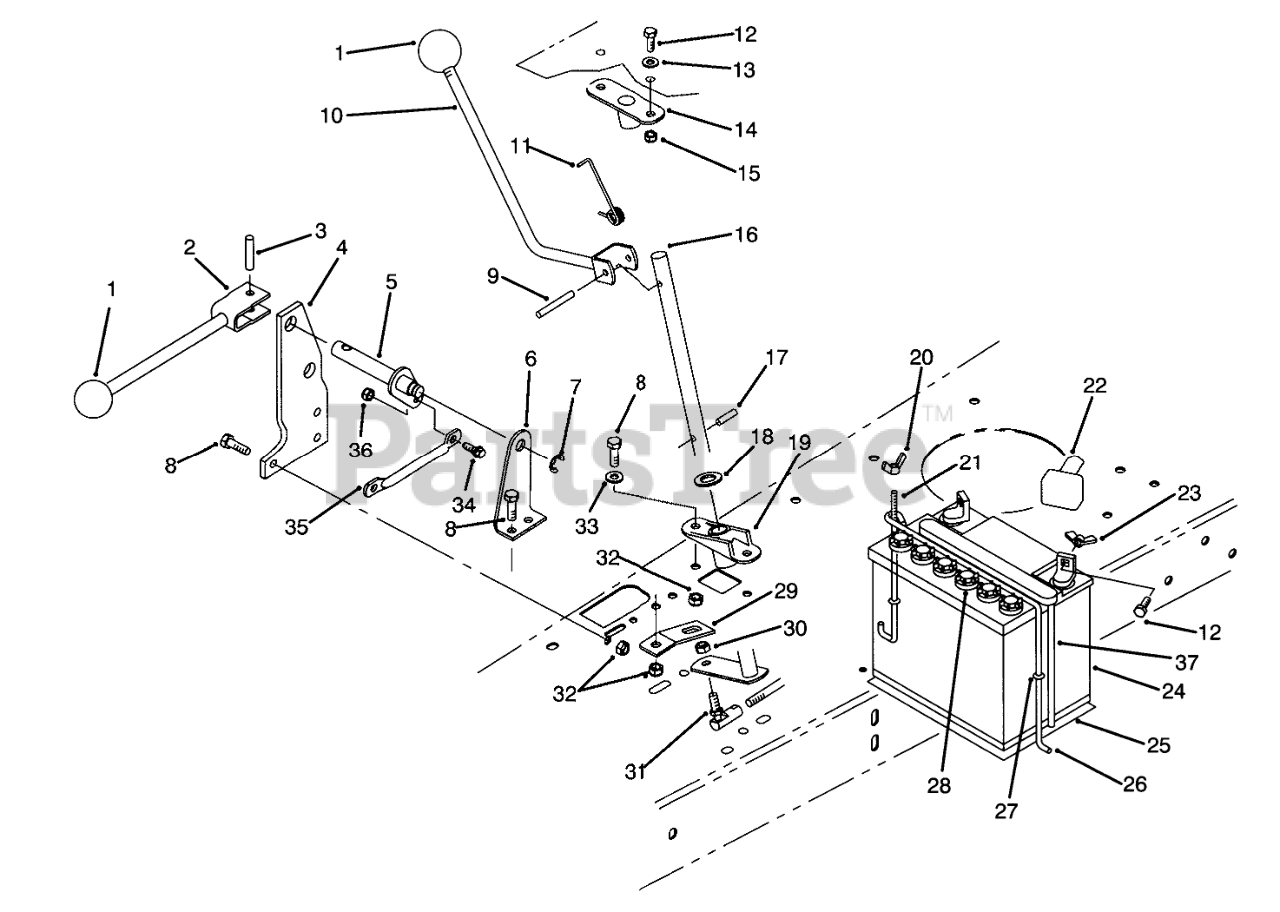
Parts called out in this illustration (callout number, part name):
2	Lever W.A.-Engage
3	PIN-ROLL
4	Pivot-Outer
5	PIVOT SHAFT WA
6	Bracket-Pivot, Inner
7	RING-RETAINING, EXTERNAL
8	SCREW-HH
9	PIN-ROLL
10	Lever W.A.-Shaft
11	SPRING-TORSION
12	SCREW-HH
13	WASHER-FLAT
14	SUPPORT-SHIFT SHAFT
15	NUT-LOCK, NI
16	SHAFT-SHIFT
17	PIN-SPRING
18	WASHER-THRUST
19	SUPPORT-LOWER SHIFTER
20	NUT-WING
21	POST-BATTERY
22	BOOT-TERMINAL
23	NUT-WING
24	Battery-12 Volt (Incl. Ref. #28 & 37)
25	PAD-SKID, ANTI
26	HOLDDOWN-BATTERY
27	O-RING
28	CAP-BATTERY
29	RETAINER-TRACTION SPRING
30	NUT-LOCK
31	JOINT-BALL
32	NUT-LOCK, NI
33	WASHER-PLAIN
34	SCREW-SHOULDER
35	LINK-BELLCRANK
36	NUT-HEX
37	TUBE-BATT DRAIN/80-2600
